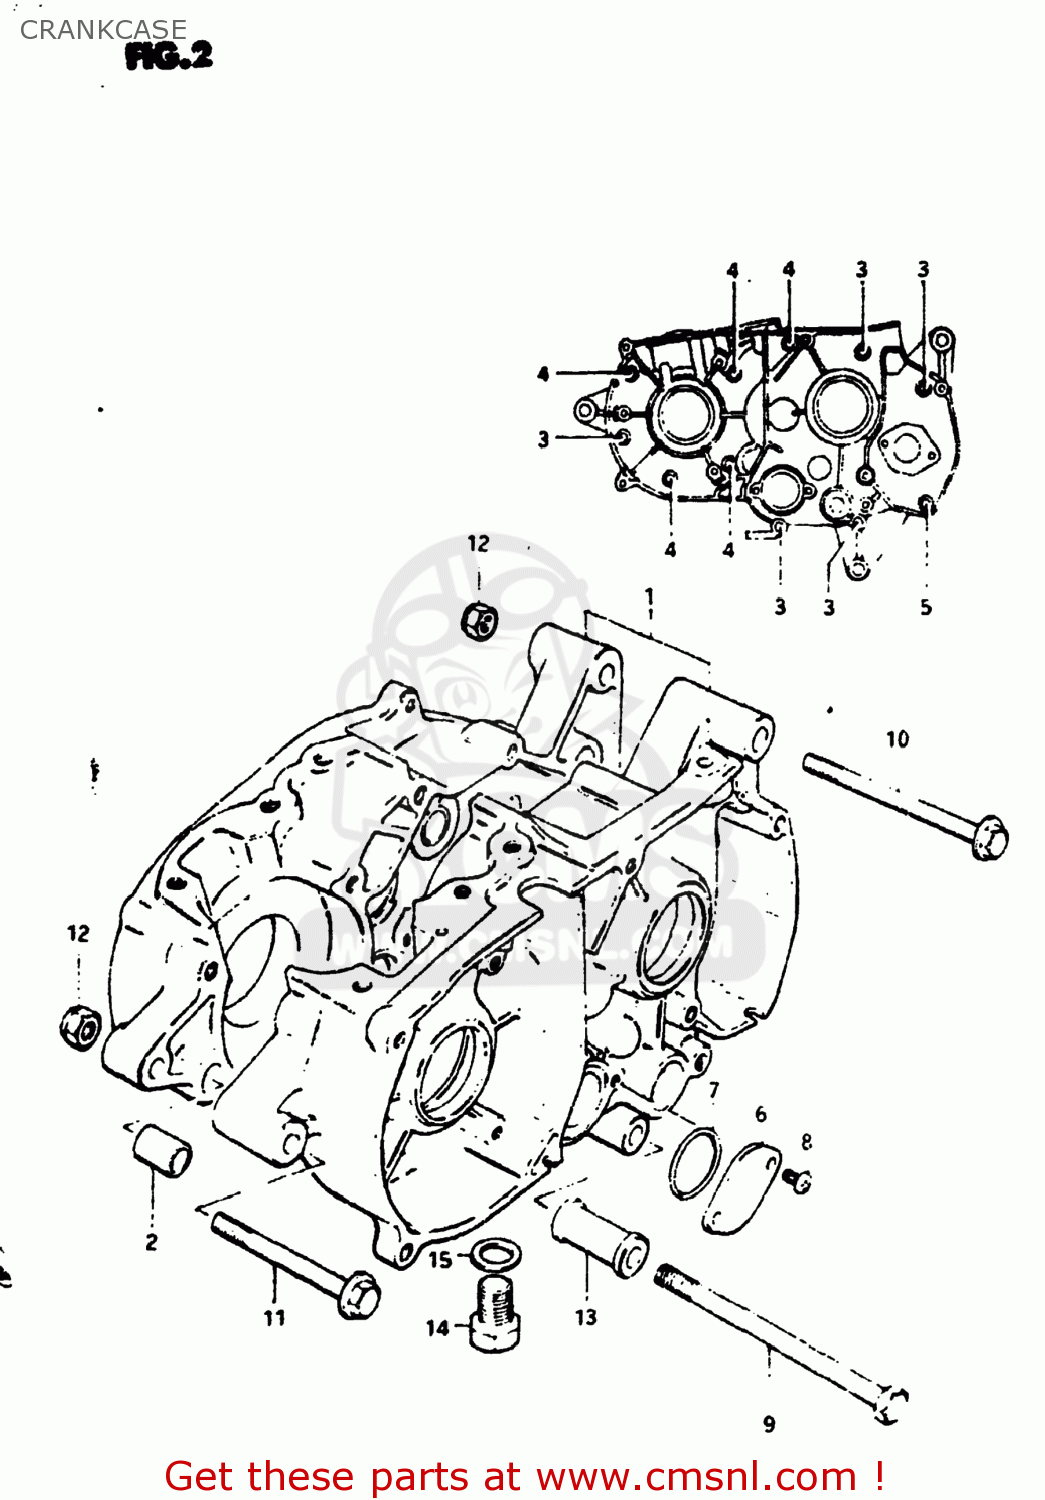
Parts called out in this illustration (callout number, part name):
1	CRANKCASE ASSEMBLY
2	PIN
3	SCREW (6X45)
4	SCREW (6X35)
5	SCREW
6	CAP,GEAR SHIFT CAM PIVOT
7	O-RING (D:2.4 ID:26.2)
8	SCREW
9	BOLT(8X230)
10	BOLT(8X100)
11	BOLT(8X70)
12	NUT
13	SPACER,ENGINE MOUNT(L:46)
14	BOLT 10X20
15	GASKET(10X14X3.6) (NAS)
